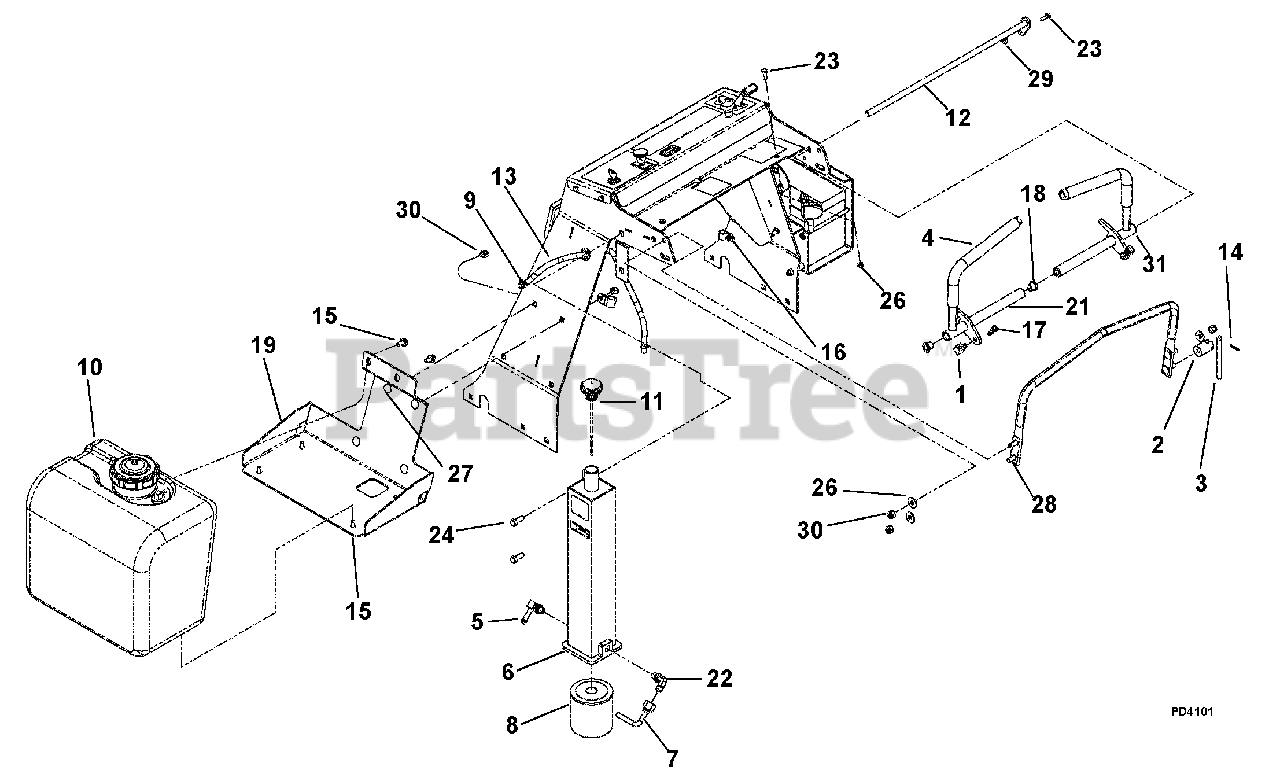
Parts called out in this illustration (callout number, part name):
1	Swivel
2	Base, Speed Control Lock
4	Grip, Control
5	Fitting, Adapter .562-18 Steel Thread
6	Hydraulic Reservoir, Inc. Decal
7	Elbow Fitting
8	Element, Oil Filter
9	Clamp
10	Fuel Tank
11	Cap
12	Shaft, Pivot
13	Hose, 1/4" ID Low Perm Fuel 50
14	Pin, Spring 5/32 x 1
15	Bolt, Hex M8 x 1.25 x 16
16	P-Clip, .500 Insulated
17	Pin, Hair Int .091 x 1.65
18	Bearing, FLG .500 x .620 x .500 Bronze
19	Bracket, Fuel Tank Mounting
20	Handle, Support
21	Weldment, RH Control Lever
22	Adapter, 2503-6-6
23	Bolt, Hex .25-20 x .75
24	Bolt, Hex .38-16 x 1.00
25	Nut, Hex .25-20
26	Washer, Flat Steel .438 x 1.00 x .083
27	Bolt, Roundhead Square Short Neck .38-16 x 1.00
28	Bolt, Roundhead Square Neck .38-16 x 1.00
29	Nut, Locking, Nylon .250-20
30	Nut, Locking, Nylon .38-16
31	Weldment, LH Control Lever
